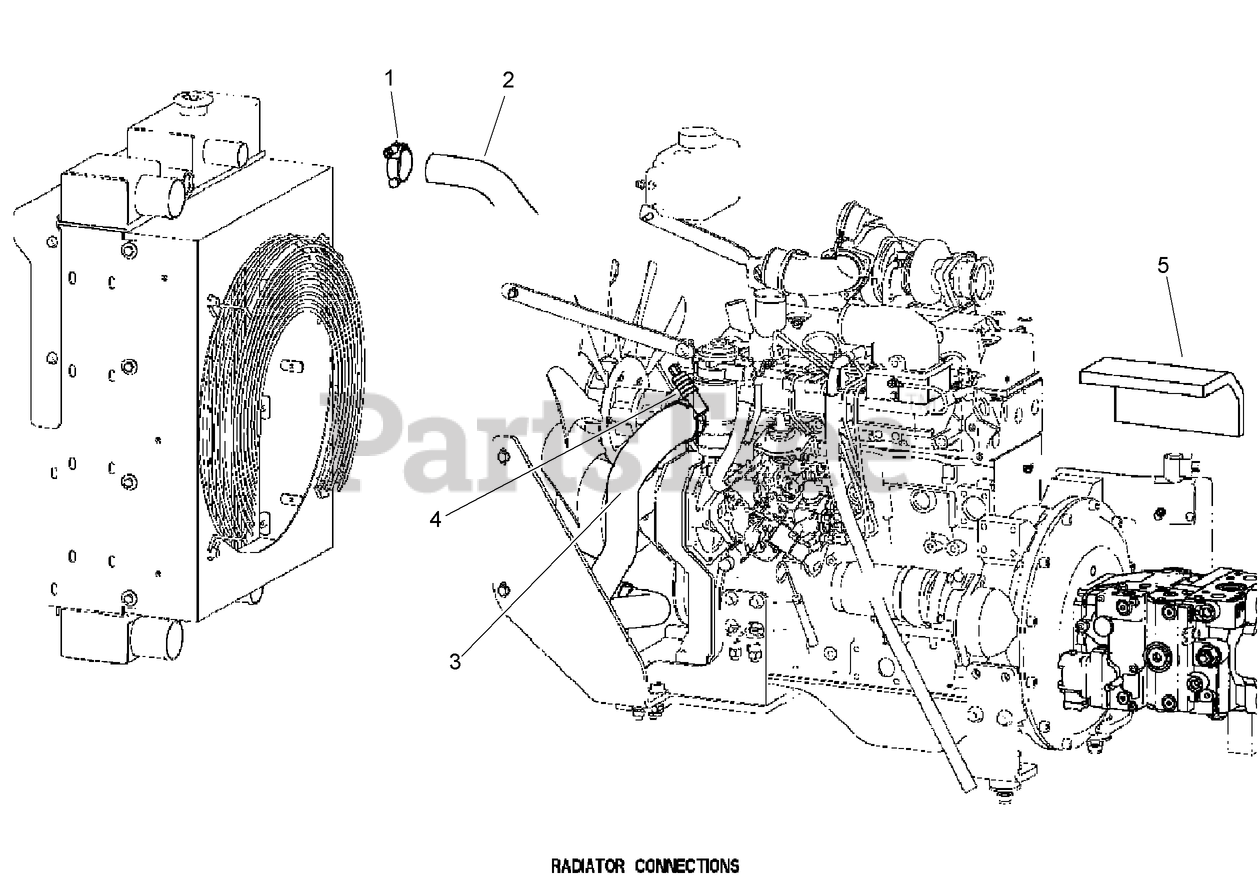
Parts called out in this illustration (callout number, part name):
1	CLAMP-HOSE (T-BOLT)
2	HOSE - Upper Radiator
3	TUBE - Lower Radiator
4	CLAMP-TORQUE, CONSTANT
5	SHIELD-HEAT
